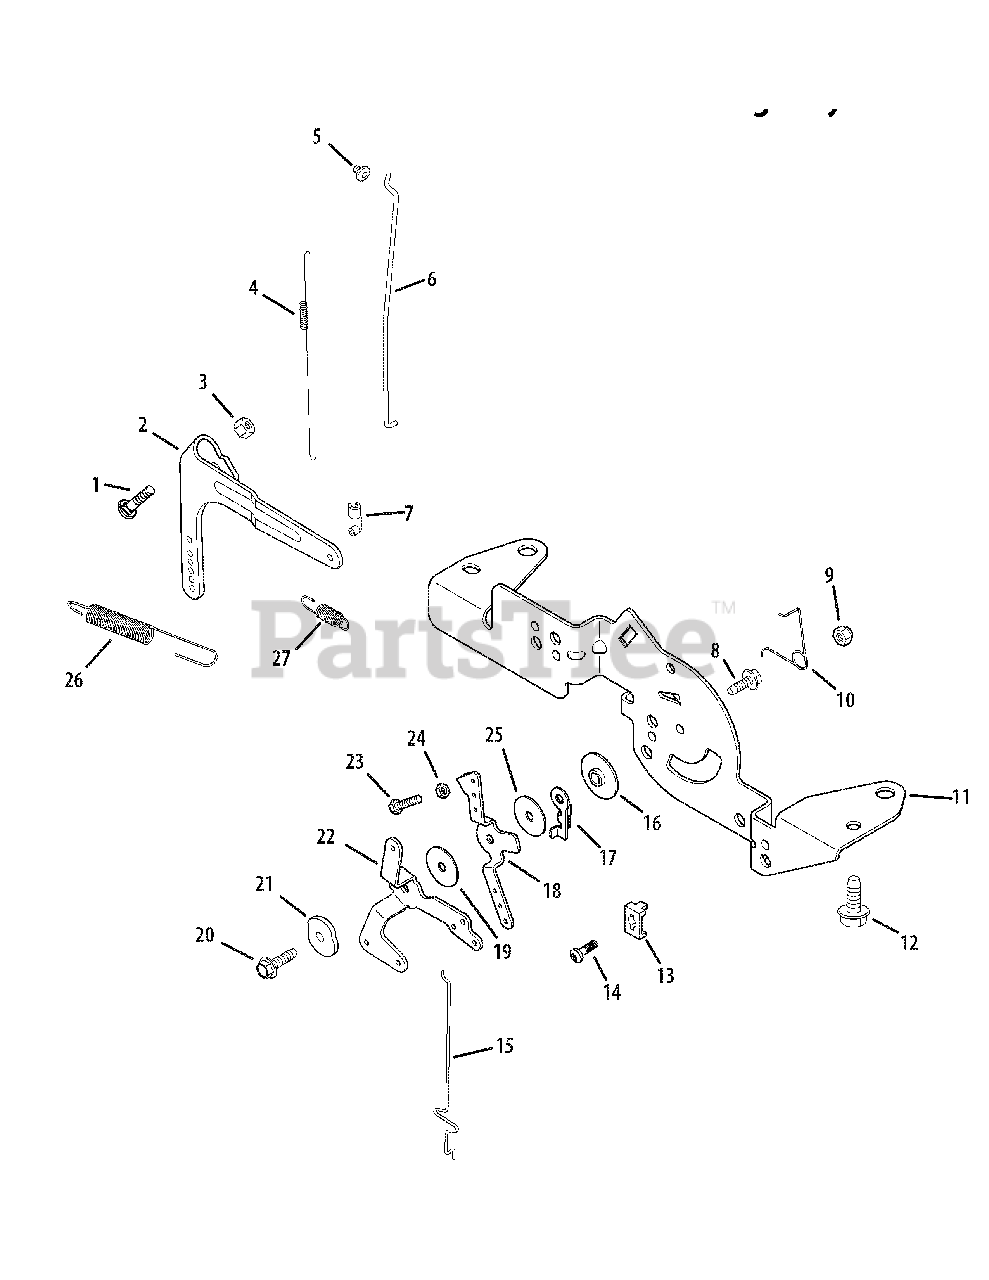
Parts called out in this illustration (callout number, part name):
1	Bolt, round hd square neck
2	Lever, governor
3	Nut, hex. flange M6x1.0
4	Spring, linkage
5	Bushing, linkage retaining
6	Linkage, throttle
7	Bushing, throttle linkage
8	Screw, hex. flange, M5x0.8x16
9	Nut, hex. lock M5x0.8
10	Spring, choke return
11	Bracket, control
12	Screw, hx. flange M6x1.0x16
13	Clamp, dual conduit
14	Screw, thread forming
15	Linkage, choke
16	Spacer, control assembly
17	Lever, throttle actuator
18	Lever, throttle control
19	Washer, plain 5.5 mm
20	Screw, hx. flange M5x0.8x20
21	Washer, spring 1/4"
22	Lever, choke
23	Screw, hex. head cap M4x0.7x25
24	Nut, hex. M4x0.7
25	Washer, plain
26	Spring, governor
27	Spring, governor
